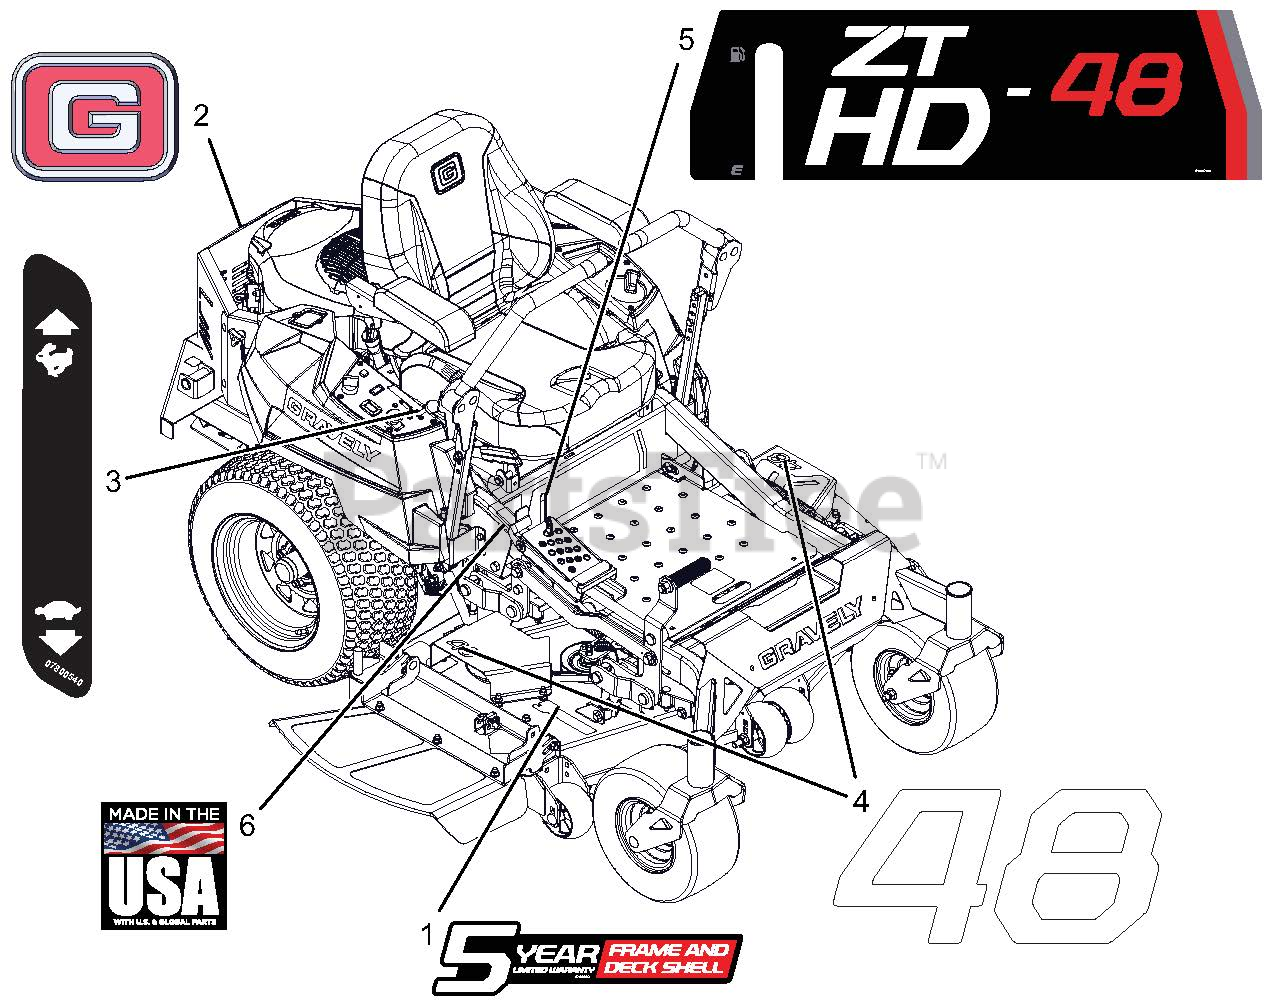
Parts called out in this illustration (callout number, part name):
1	DECAL, DECK 5 YEAR-GRAVELY
2	DECAL, GRAVELY BRAND
3	DECAL, DASH DECAL
4	DECAL, 48"
5	DECAL - 48HD
6	DECAL, MADE IN USA
